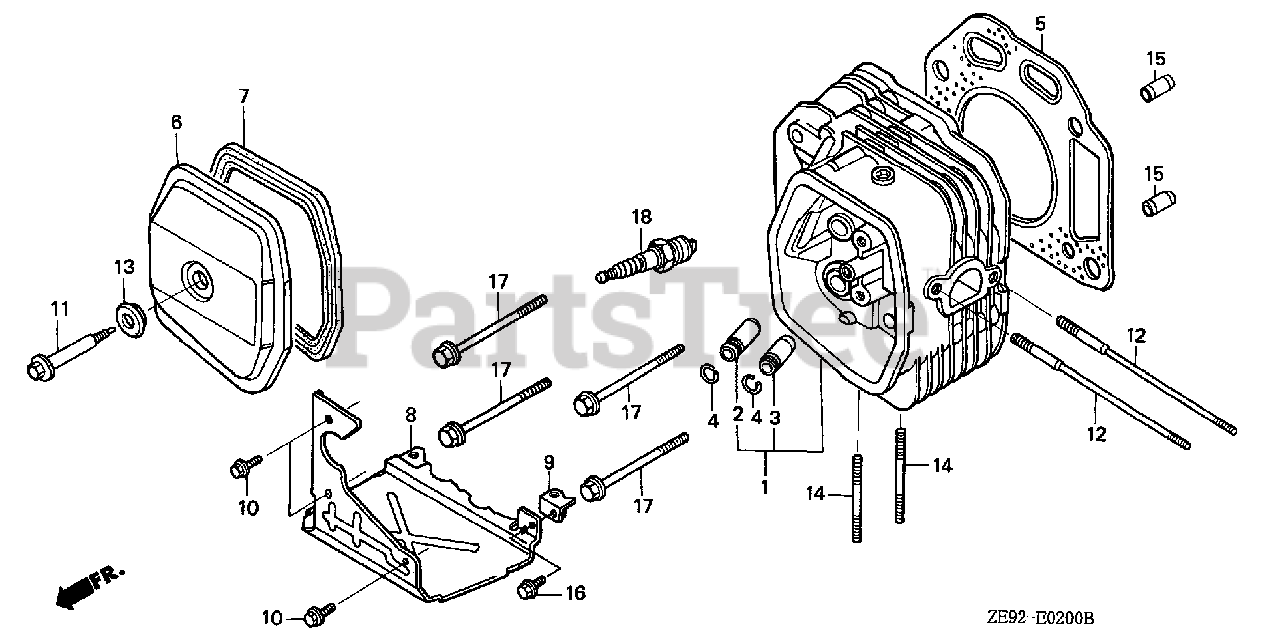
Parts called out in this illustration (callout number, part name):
1	CYLINDER HEAD
2	GUIDE, VALVE (OVER SIZE)
3	GUIDE, EX. VALVE (OVER SIZE)
4	CLIP, VALVE GUIDE
5	GASKET, CYLINDER HEAD
6	COVER, HEAD
7	GASKET, HEAD COVER
11	BOLT, HEAD COVER
12	BOLT, STUD (8X131.5)
13	WASHER, HEAD COVER
14	BOLT, STUD (8X32)
15	PIN, DOWEL (12X20)
17	BOLT, FLANGE (10X80)
18	SPARK PLUG (BPR5ES) (NGK)
